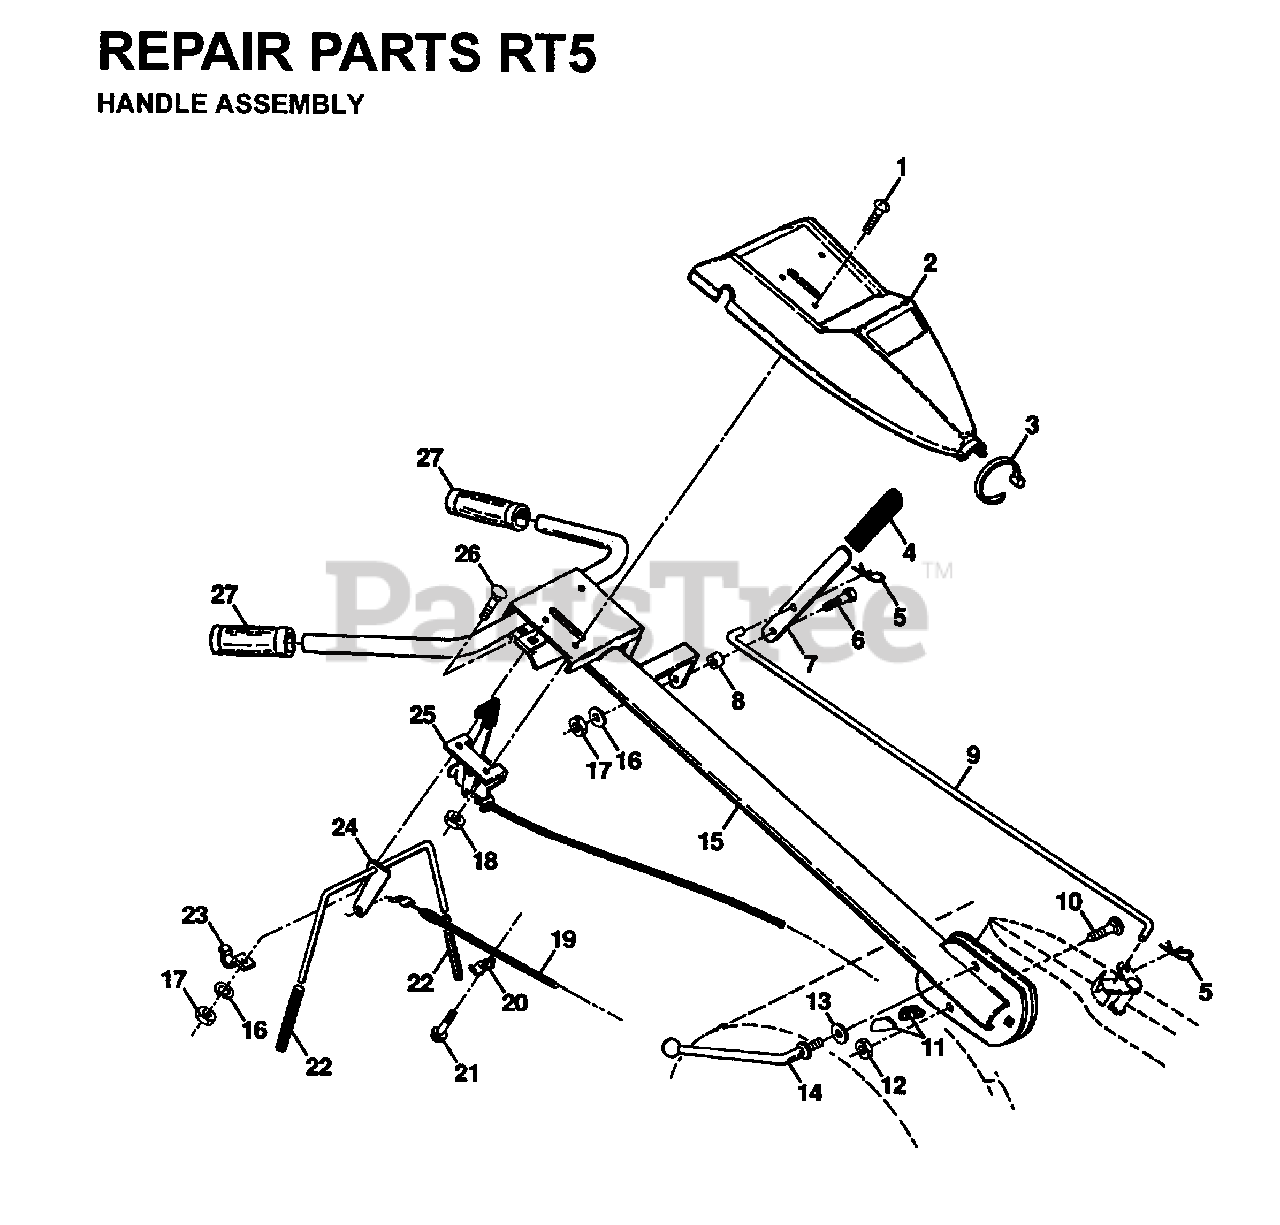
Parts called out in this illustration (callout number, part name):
1	SCREW
3	TIE CABLE CRT
4	GRIP T
5	RETAINER M
6	SHOULDER BOLT ST
7	SHIFT HANDLE CRT
8	GROMMET.RUBBER.CRT.TILLER
9	SHIFT ROD CRT
12	LOCKNUT
13	WASHER
14	LEVER.LOCK.CRT
16	LOCKWASHER
17	NUT
19	CABLE, CLUTCH 48 "Z"
20	CONDUIT CLIP T
22	GRIP BAR CRT(1)
23	CLAMP.BAR.CRT.BLACK
24	BAR ASSY CONTROL
25	CONT,THROTTLE
27	HAND.GRIP.NLA
